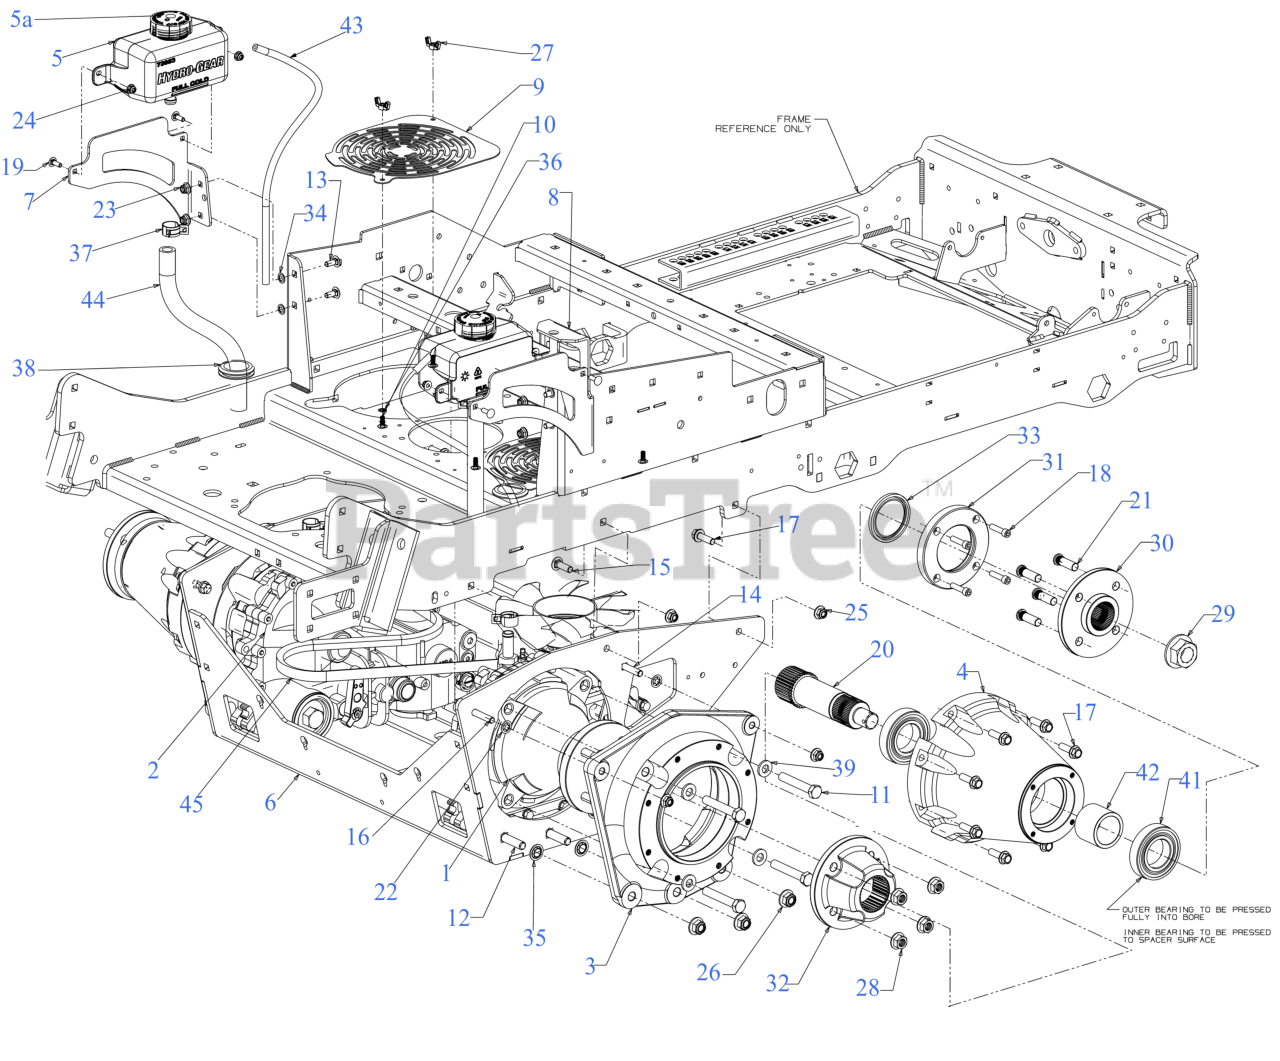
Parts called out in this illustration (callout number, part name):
1	TRANSMISSION (RH)
2	TRANSMISSION (LH)
3	ADPT:MT:HYDRO:DUAL:MACH
4	ADPT:SUPT:OUPUT:DUAL:MACH
5	1L EXPANSION TANK
6	BRKT ASM:TRANS:HG:DW
7	TANK MOUNT BRACKET (LH)
8	TANK MOUNT BRAKET (RH)
9	TRANSMISSION COVER PLATE
10	CARRIAGE BOLT 1/4-20 x .62
11	SCREW-HEX 1/2-13 x 3.00
12	CARRIAGE BOLT 1/2-13 GR5
13	CARRIAGE BOLT 5/16-18 x .75
14	CARRIAGE BOLT 3/8-16 x 1.75 GR5
15	CARRIAGE BOLT 3/8-16 X1.25 GR5
16	SCREW 3/8-16 x 2.25 GR5
17	SCREW 3/8-16 x 1.25 GR5
18	SCREW 5/16-18X1.25
19	SCREW 1/4-20 x .75 GR5
20	SHF:WHL:DUAL:SPLINED
21	RIBBED NECK STUD
23	FLANGE LOCK NUT 5/16-18
24	FLANGE LOCK NUT
27	WING NUT 1/4-20
28	HEX FLANGE NUT 1/2-20 GR8
29	NUT:HEXFLG:1.00-14:GR5:TOPLK
30	WHEEL HUB (OUTER)
31	CVR:SEAL:AXLE
32	HUB:ADAP:SHF
33	SHAFT SEAL 57.15X76.2X6.35
36	RETAINER-BOLT .25ID x .50OD
37	HOSE CLAMP
38	RUBBER GROMMET (1.50X2.13X.563)
39	FLAT WASHER .510 x 1.000 x .125
41	BALL BEARING 45X85X19
42	SPACER 1.775X2.253X1.805
43	VENT HOSE 3/16 ID 45"LG
44	OIL HOSE 5/8 ID X 12.5 LG
45	V-BELT 66.34"
